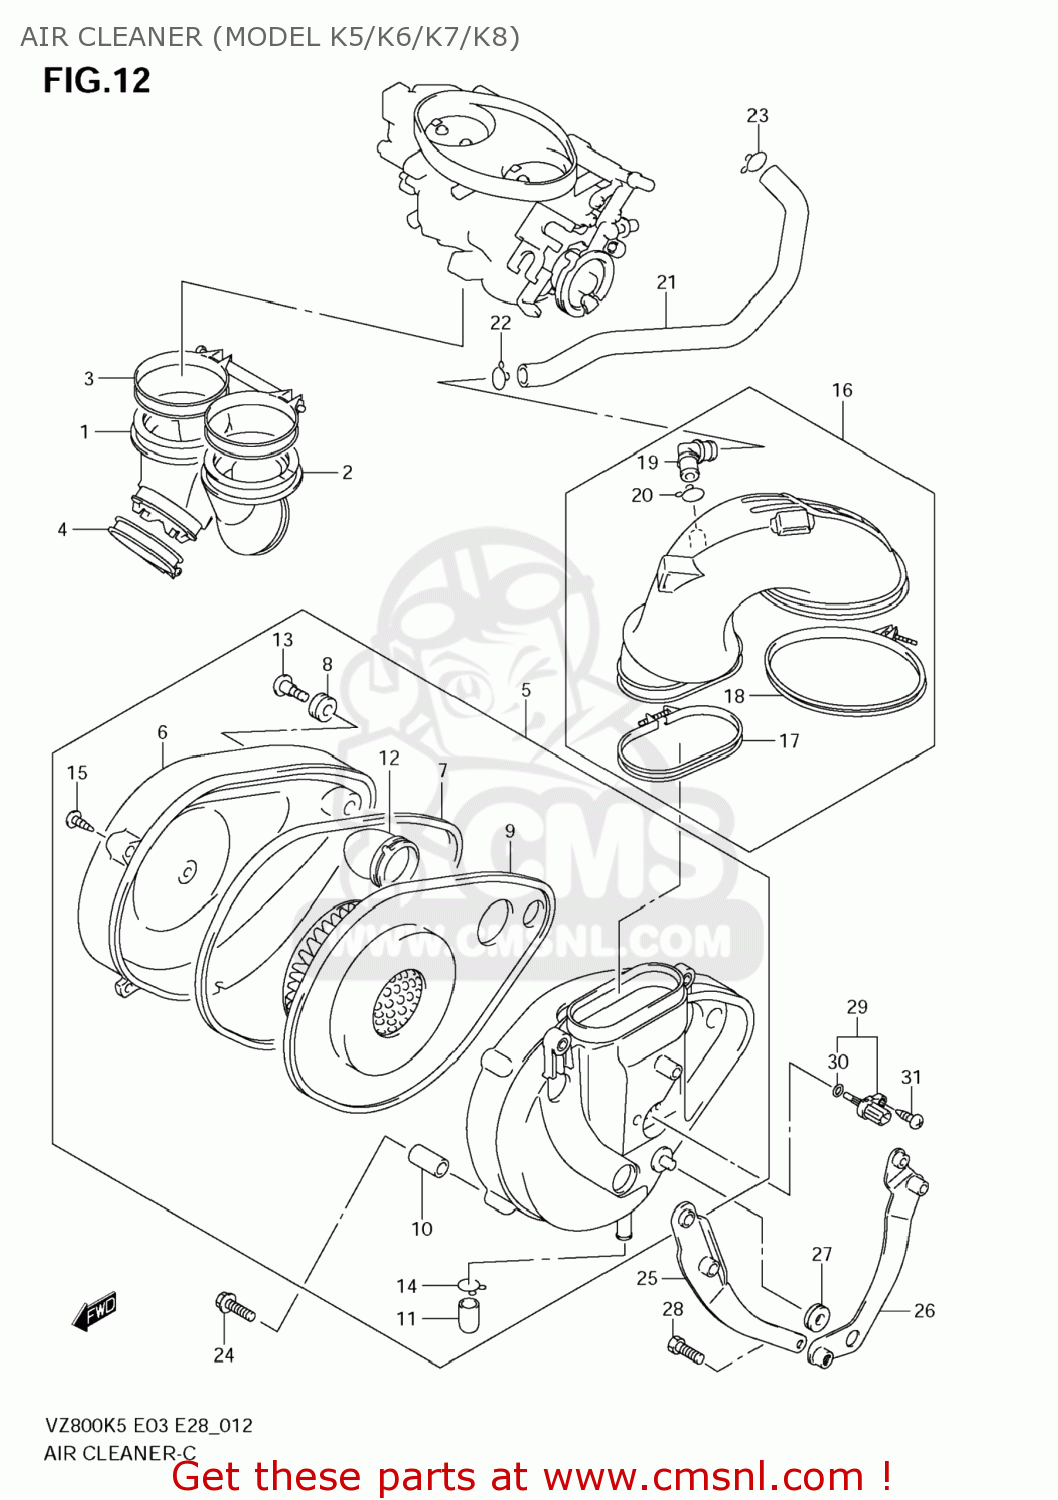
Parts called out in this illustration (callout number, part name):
1	PIPE,INTAKE NO.1
2	PIPE,INTAKE NO.2
3	CLAMP,INTAKE PIPE
4	CLAMP,INTAKE PIPE
5	CASE ASSY,AIR CLEANER
6	CAP,AIR CLEANER
7	GASKET (NAS)
8	CUSHION
9	FILTER,AIR CLEANER
10	COLLAR
11	PLUG
12	TUBE,INLET
13	SCREW(6X20)
14	CLIP
15	SCREW
16	TUBE ASSY,OUTLET
17	CLAMP
18	CLAMP
19	JOINT
20	CLIP
21	TUBE,BREATHER
22	CLIP
23	CLAMP
24	BOLT(6X20)
25	BRACKET,AIR CLEANER FR
26	BRACKET,AIR CLEANER RR
27	CUSHION
28	BOLT
29	SENSOR,AIR TEMP
30	O RING
31	SCREW
